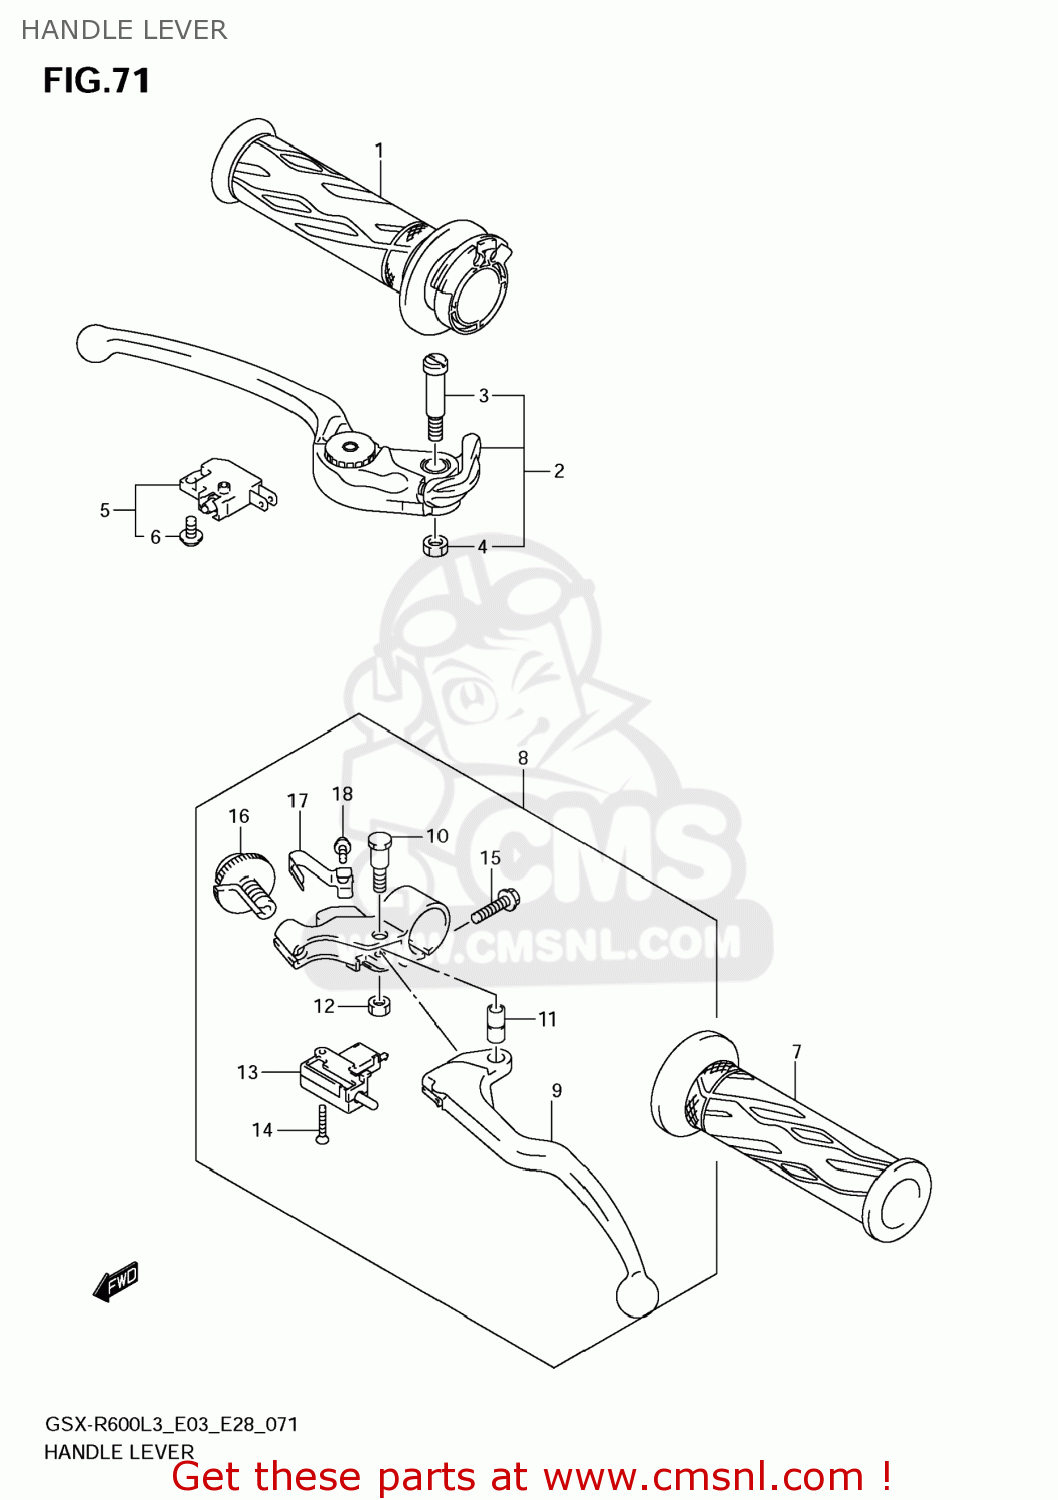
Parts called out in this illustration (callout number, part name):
1	GRIP,THROTTLE
2	LEVER ASSY,BRAKE
3	BOLT,LEVER PIVOT
4	NUT
5	SWITCH ASSY,FR BRAKE
6	SCREW
7	GRIP,L
8	LEVER ASSY,CLUTCH
9	LEVER,CLUTCH
10	BOLT,CLUTCH LEVER PIVOT
11	COLLAR
12	NUT
13	SWITCH,CLUTCH
14	SCREW
15	BOLT
16	NUT,ADJUSTER
17	SPRING,ADJUST
18	SCREW,SPRING
